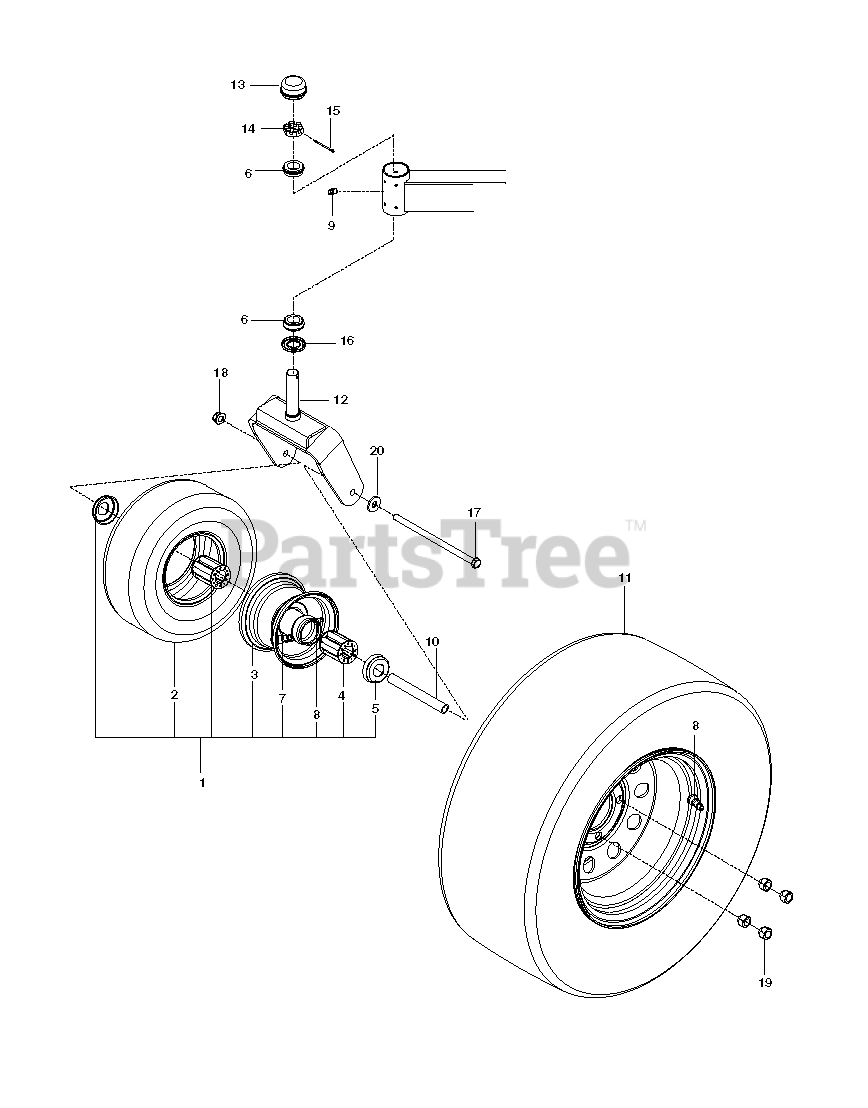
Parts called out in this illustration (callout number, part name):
1	TIRE.ASSEM.13X5-6.SMOOTH.SILVE
2	TIRE - FRONT
3	RIM
4	ROLLER BEARING
5	BEARING RETAINER
6	TAPERED ROLLER BRG
7	VALVE STEM TR-412
8	NUT 10-24 NYLOC
10	SPACER, CASTER
11	TIRE/WHEEL.ASM.22X9.5-10
12	CASTER YOKE ORANGE
13	GREASE CAP
14	NUT 1"C HEX SLOTTED
15	COTTER PIN 1/8 X 2
17	SCREW 1/2C X 7 1/2 HEX CAP
18	NUT, 1/2-13 HEX FLG NYLOC ZD
19	LUG NUT 1/2F
20	WASH USS FLAT 1/2
